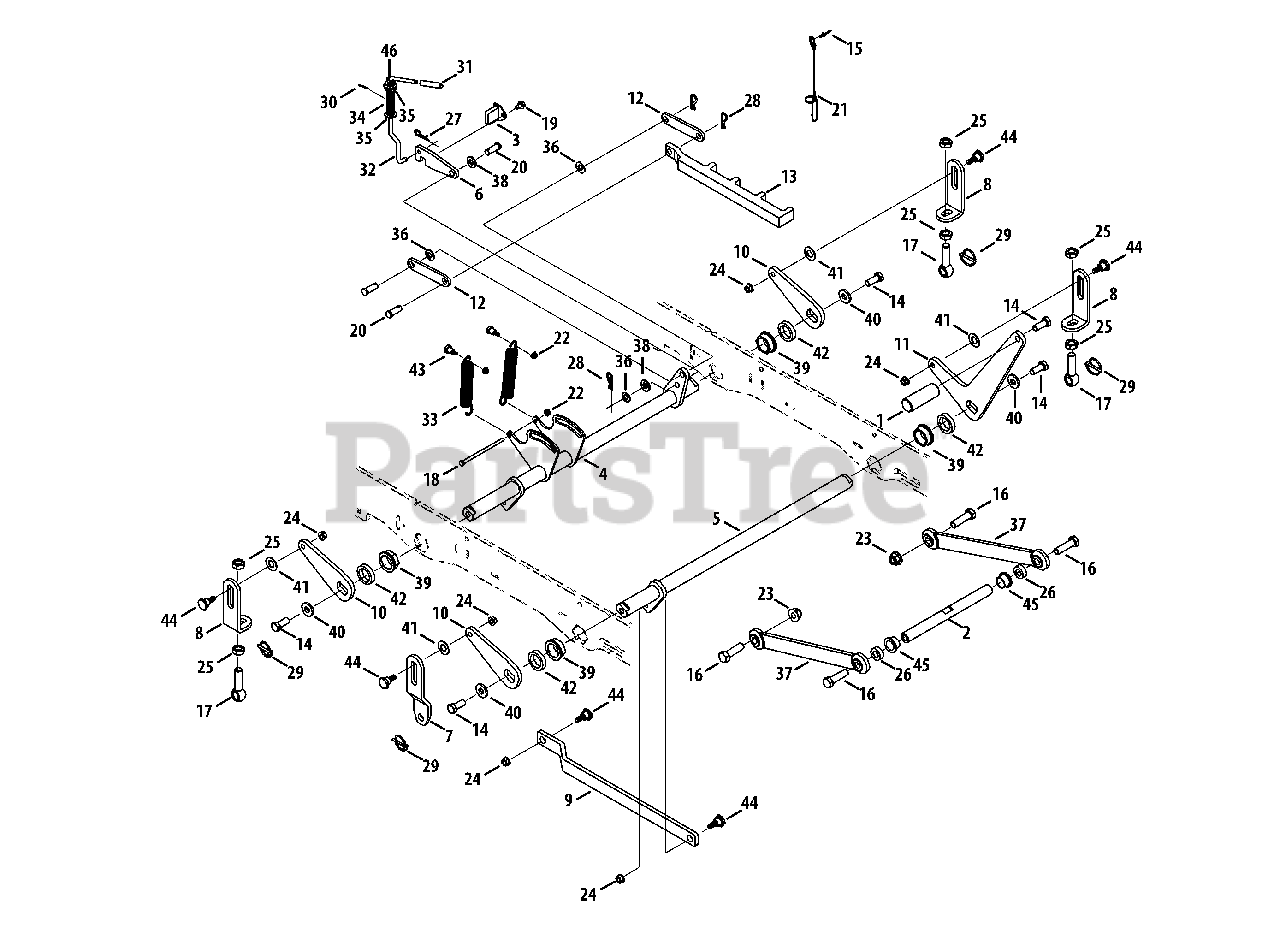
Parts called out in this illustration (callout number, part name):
1	Deck Lift Foot Pedal
2	Front Lift Shaft
3	Lift Lock Mount
4	Deck Lift Shaft
5	Deck Lift Shaft, Front
6	Latch Lock Bracket
7	Lift Link Arm
8	Deck Adjustment Lift Link Arm
9	Deck Lift Bar, Front
11	Deck Lift Foot Pedal
12	Deck Index Link Arm
13	Lift Index Slider Arm
14	Hex Cap Screw, 1/2-13 x 1.25
15	Rivet, 3/16 x .325
16	Hex Cap Screw, 5/8-11 x 2.25
17	Eye Bolt, 5/8-18 x 2.63
18	Hex Cap Screw, 1/4-20 x 5.00
19	Screw, 5/16-18 x .500
20	Clevis Pin, .500 x 1.25
21	Clevis Pin, .438 x 1.5
22	Nut, 1/4-20, Flangelock
23	Nut, 5/8-11, Flangelock
24	Nut, 3/8-16, Flange Centerlock
25	Jam Nut, 5/8-11
26	Spacer, .635 x 1.25 x .445
27	Click Pin, .092 x 1.64
28	Internal Cotter Pin
29	Lynch Pin, .1875
30	Cotter Pin, 3/32 x .750
31	Lift Handle Grip
32	Lift Lock Rod
33	Extension Spring, .969 OD x 6.180
34	Compression Spring, .656 OD x 2.445
35	Bevel Washer, .340 x .872 x .060
36	Washer, .510 x 1.00 x .125
37	Deck Rod Assembly
38	Washer, .510 x 1.00 x .125
39	Hex Flange Bearing
40	Washer, .531 x 1.25 x .181
41	Washer, .640 x 1.25 x .050
42	Spacer, 1.27 x 1.75 x .375
43	Shoulder Screw, .437 x .50, 1/4-20
44	Shoulder Screw, .625 x .442, 3/8-16
45	Bushing, 1.00 x 1.50 x .750
46	Bearing, .385 ID
